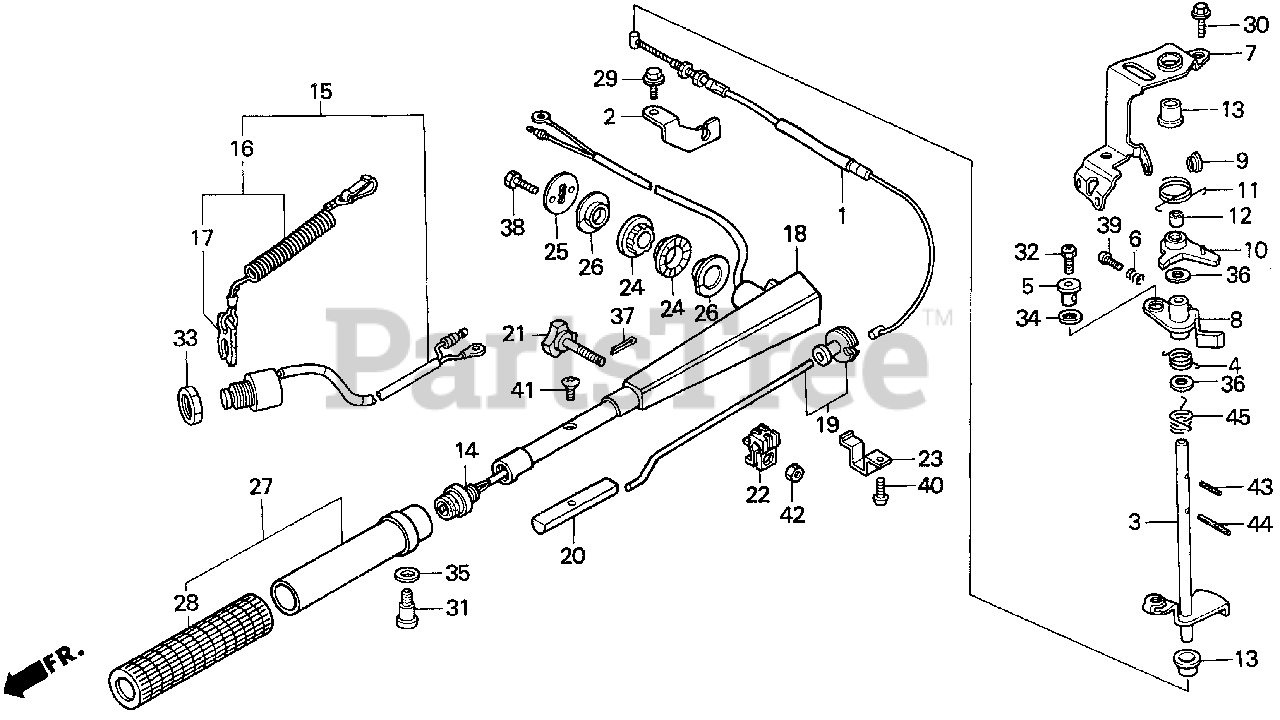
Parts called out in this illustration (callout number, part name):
1	CABLE, THROTTLE
2	HOLDER, CABLE
3	SHAFT, THROTTLE
4	SPRING, RETURN
5	HOLDER, THROTTLE ROD
7	STAY, THROTTLE SHAFT
8	LINK, THROTTLE
9	GUIDE, THROTTLE SHAFT
10	POWL, NEUTRAL START
11	SPRING, POWL
12	COLLAR, POWL
13	BUSH, SHAFT
14	SWITCH ASSY., STOP (NOT AVAILABLE)
18	HANDLEBAR *NH210MC* (AQUA SILVER METALLIC-C)
19	REEL, THROTTLE
20	WEIGHT, HANDLEBAR
21	BOLT, FRICTION
22	BLOCK, THROTTLE FRICTION
23	STAY A, THROTTLE REEL
24	RUBBER, HANDLE MOUNTING
25	PLATE, HANDLEBAR
26	COLLAR, HANDLEBAR
27	PIPE, GRIP
29	BOLT, FLANGE (6X12)
30	BOLT, FLANGE (6X14)
31	BOLT, PIPE GRIP
32	BOLT, RECESSED (5X8)
34	WASHER, NYLON (9MM)
35	WASHER (7.5MM)
36	WASHER, PLAIN (10MM)
37	PIN, SPLIT (2.0)
38	BOLT, HEX. (6X16)
39	SCREW, PAN (4X16)
40	SCREW, PAN (5X12)
41	SCREW, OVAL (6X12)
42	NUT, HEX. (6MM)
43	PIN, SPRING (3X18)
44	PIN, SPRING (3X32)
45	SPRING, THROTTLE ARM
